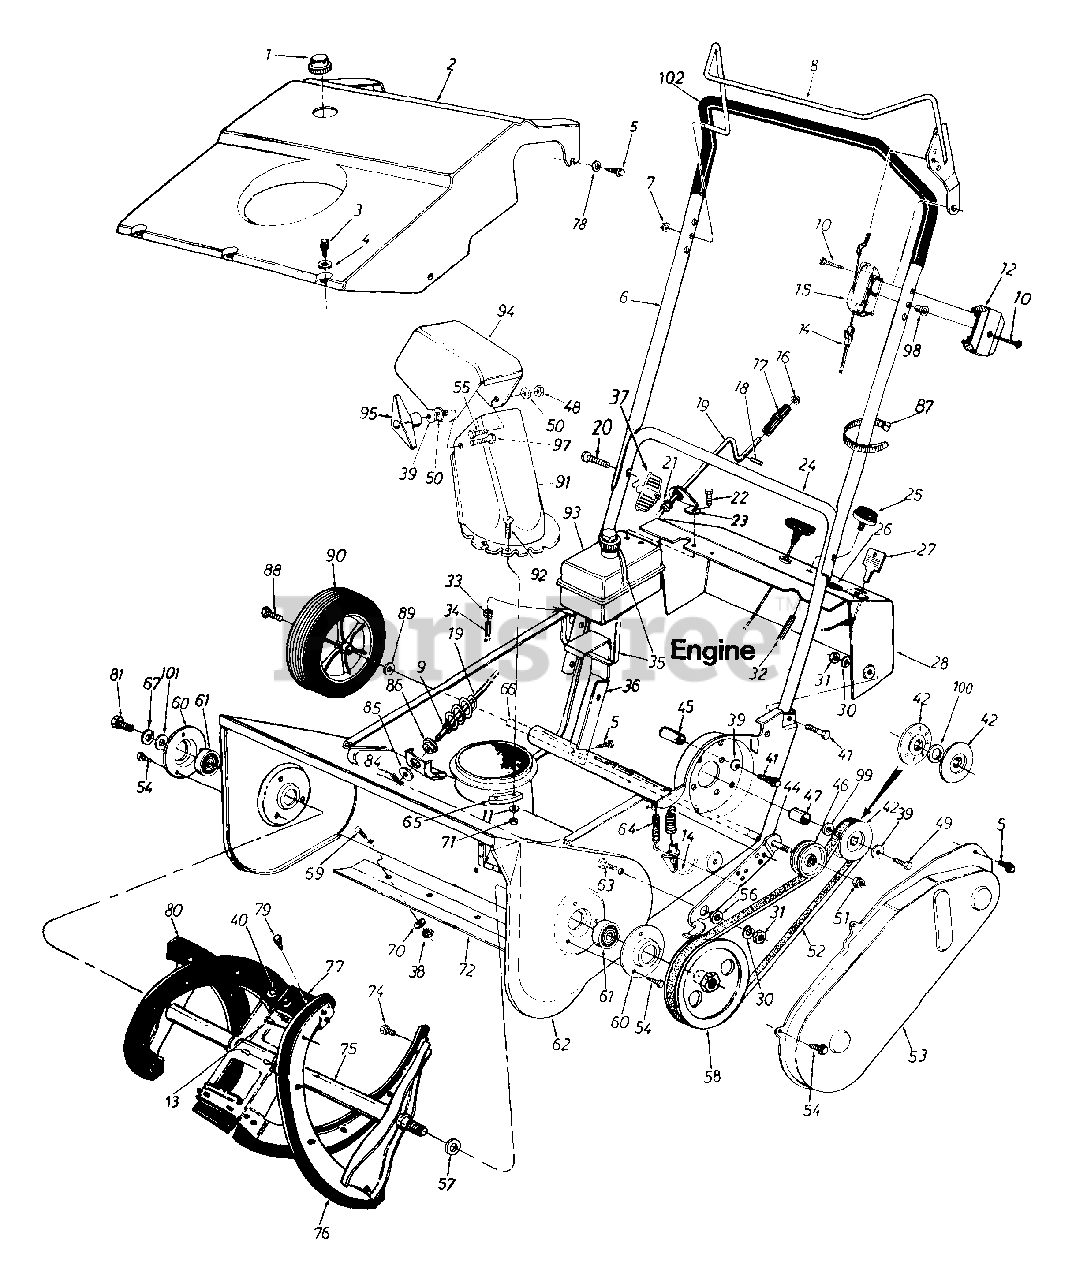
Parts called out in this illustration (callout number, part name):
1	Gas Tank Cap
2	21" Shroud
3	Hex B-Tap Scr. #10 x .38"
4	Spr.-Wash. .206" I.D. x .448"
5	Hex L-Wash. Hd. AB-Tap 1/4 x .62" Lg.
8	Control Handle Ass'y. - L.H.
9	Fl-Wash. .385" I.D. x .62"
10	Truss Mach. Hi-B Tap Scr. #12 x 1.5" Lg.
11	Fl-Wash. .281" I.D. x .5" O.D.
12	Control Panel Half
13	Pop Rivet .187" Dia.
14	Clutch Cable 35" Lg.
15	Control Panel Half
16	Push Cap 3/8" Rod
17	Knob - 3/8" Dia. Hole
18	Roll Pin 1/8" Dia. x .63" Lg.
19	Chute Crank Ass'y.
20	Curved Hd. Bolt 5/16-18 x 2" Lg.
21	Plastic Bushing .38" I.D.
22	Hex Nut 1/4-20 Thd.
23	Upper Chute Crank Brkt.
24	Lower Handle
26	Plastic Plug
27	Plastic Key (Tech. Eng.)
31	Hex Nut 5/16-18 Thd.
32	Primer Hose - 11" Lg.
33	Hose Clamp - 1/2" Dia.
34	Gas Line - 15" Lg.
35	Cable Tie - 17.75" Lg.
38	Hex Jam Nut 1/4-20 Thd.
39	Bell-Wash. .345" I.D. x .88"
40	Torx AB-Tap Scr. 1/4 x .62" Lg.
41	Hex Bolt 5/16-18 x 1.5" Lg.
42	3/8" "V"-Pulley Half .625" I.D. x 6.0" O.D.
44	Idler Brake Brkt. Ass'y.
45	Spacer .325" I.D. x .625" O.D. x .875"
46	Fl-Idler w/Flanges 2.12" O.D.
47	Spacer .635" I.D. x .89" O.D. x .57"
48	Hex L-Nut 5/16-18 Thd.
49	Hex Bolt 5/16-24 x .75" Lg.
50	Fl-Wash. .344" I.D. x 1.25"
51	Hex Patch L-Nut 3/8-24 Thd.
52	V-Belt
54	Hex B-Tap Scr. 1/4" x .38" Lg.
55	Carriage Bolt 5/16-18 x .75"
56	Shld. Spacer .50" Dia. x .27"
57	Fl-Wash. .510" I.D. x 1.0" O.D.
58	3/8" "V"-Pulley 1/2-20 L.H. x 6"
60	Bearing Cup
61	Ball Bearing
64	Extension Spring 1.12" Lg.
65	Chute Flange Keeper
66	Wheel Axle 1/2" O.D. x 20.6" Lg.
67	L-Wash. 1/4" I.D.
69	Carriage Bolt 1/4-20 x .50"
70	Fl-Wash. .281" I.D. x .73"
71	Hex L-Nut 1/4-20 Thd.
72	Shave Plate
74	Hex Wash. B-Tap Scr. 1/4 x .62" (Spec.)
75	Auger Ass'y. 21"
76	Rubber Spiral - L.H.
77	Rubber Paddle
79	Hex Wash. B-Tap Scr. #10 x .62" Lg.
80	Rubber Spiral - R.H.
81	Hex Wash. TT-Tap Cl-Scr. 1/4-20 x .75" Lg.
84	Cotter Pin 3/32" Dia. x .75"
85	Fl-Wash. .406" I.D. x 1.25"
86	Hex Bushing .385" I.D.
87	Cable Tie
88	Hex Tap Scr. 3/8-24 x .5" Lg.
89	Fl-Wash. .510" I.D. x .75"
90	Wheel & Tire Ass'y. 7" x 1.5"
91	Lower Chute
92	Truss Mach. Scr. 1/4-20 x .75"
93	Fuel Tank - One Qt.
94	Upper Chute
97	Carriage Bolt 5/16-18 x 1"
98	Control Disc Pin
99	Fl-Wash. .635" I.D. x 1.04" O.D.
100	Fl-Wash. .635" I.D. x .93" O.D.
101	Fl-Wash. .25" I.D. x .93"
102	Foam Grip
